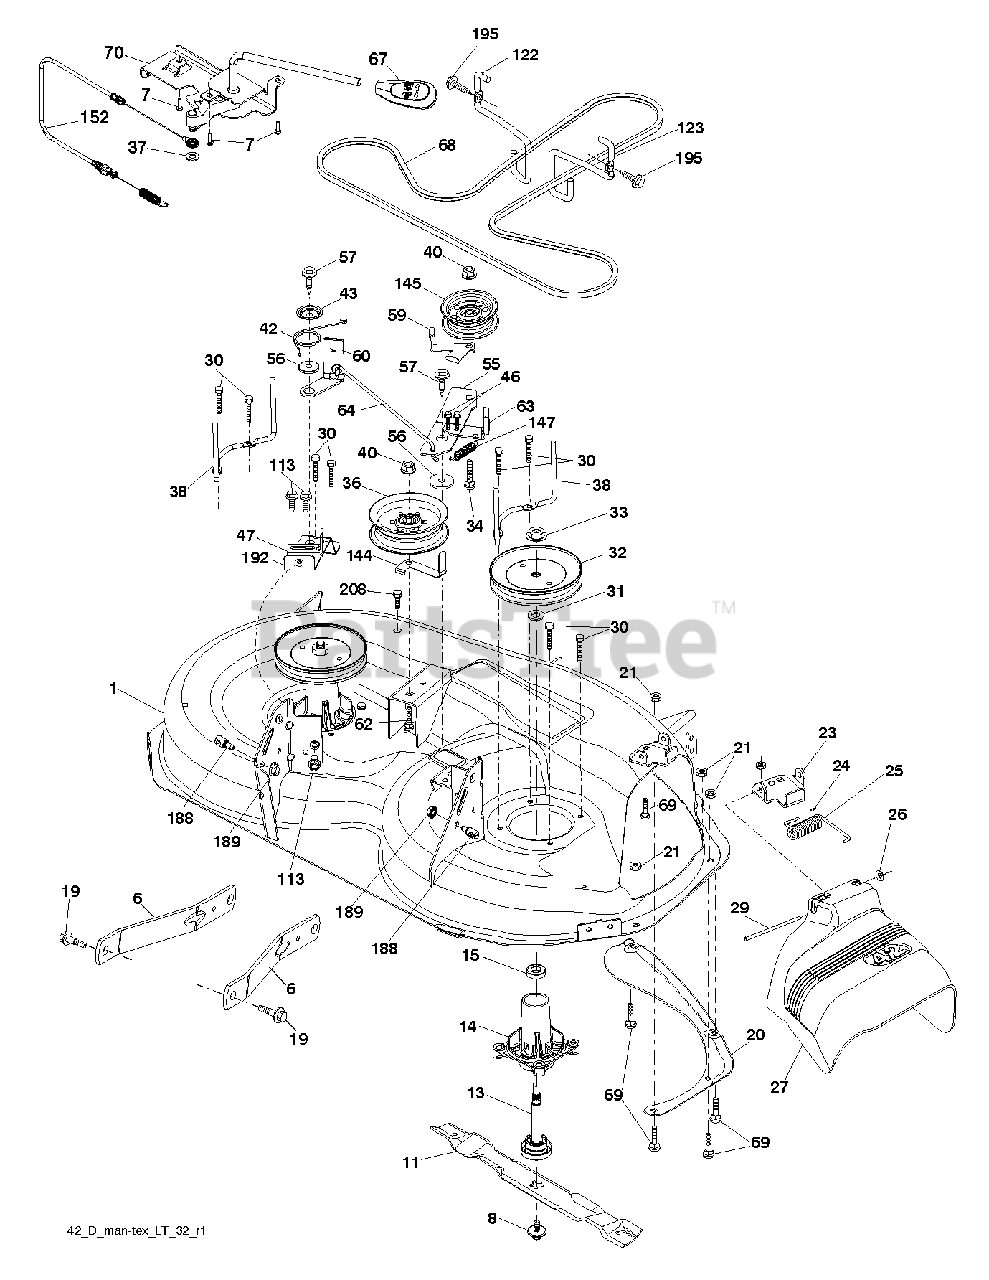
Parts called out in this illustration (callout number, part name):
6	ARM.SUSPENSION.MOWER.R
7	SCREW.#10 X 0.750.BOS (2 2)
8	BOLT.WASHER.ASM.7/16-2
11	42" HI-LIFT BLADE
13	SHAFT.ASM.MDRL.N/GREASE.38
14	HOUSING.MANDREL.4PT.
19	BOLT.SHOULDER
20	BAFFLE.VORTEX
21	LOCKNUT
23	BRKT.DEFLECTOR.38"2005+
24	CAP-SLEEVE LT
25	SPRING.TORSION.DEFLECT
26	NUT PUSH M
27	SHIELD.DEFLECTOR.MOWER.42"BLAC
29	ROD.HINGE
30	SCREW, WASHER HEAD
31	WASHER.SPACER.MANDREL
32	PULLEY.MANDREL.5.438.PD
33	NUT.FLANGE.LOCK.TOP
34	BOLT.3/8-16X1.50
36	PULLEY.IDLER.2006
38	KEEPER.BELT.MANDREL.PULLEY
40	NUT LOCK FLG 3/8-16 UNC
42	SPRING.TORSION.BRAKE
43	SRPING.TORSION.RETAINE
46	SCREW.1/4-20X5/8
47	BRKT.CLUTCH.CABLE
55	IDLER.ARM.42"
56	SPACER.RETAINER
57	SCREW 3/8-16X1
59	GUARD, BELT
60	ARM BRAKE MOWER
62	BOLT
64	LINK BRAKE
67	HANDLE.CLUTCH.CABLE.LT
68	BELT.DECK.DRIVE.42"
69	BOLT
70	CLUTCH.ASM.MANUAL.LT.TEX
113	BOLT.5/16HEX.WHS.HD
122	KEEPER BELT ENGINE LH
123	KEEPER BELT RH
144	KEEPER.BELT.MOWER
145	PULLEY.IDLER.48"PRIMARY
147	RETURN SPRING
152	CABLE.CLUTCH.MANUAL.
188	STUD.FASTNER.W/ANTI-ROTATE
189	NUT LOCK HEX FLANGE 5/16-18
192	BRKT.BRAKE.STAND.LH.
195	SCREW, 3/8-16X3/4
208	SCREW 3/8-16X1/2
